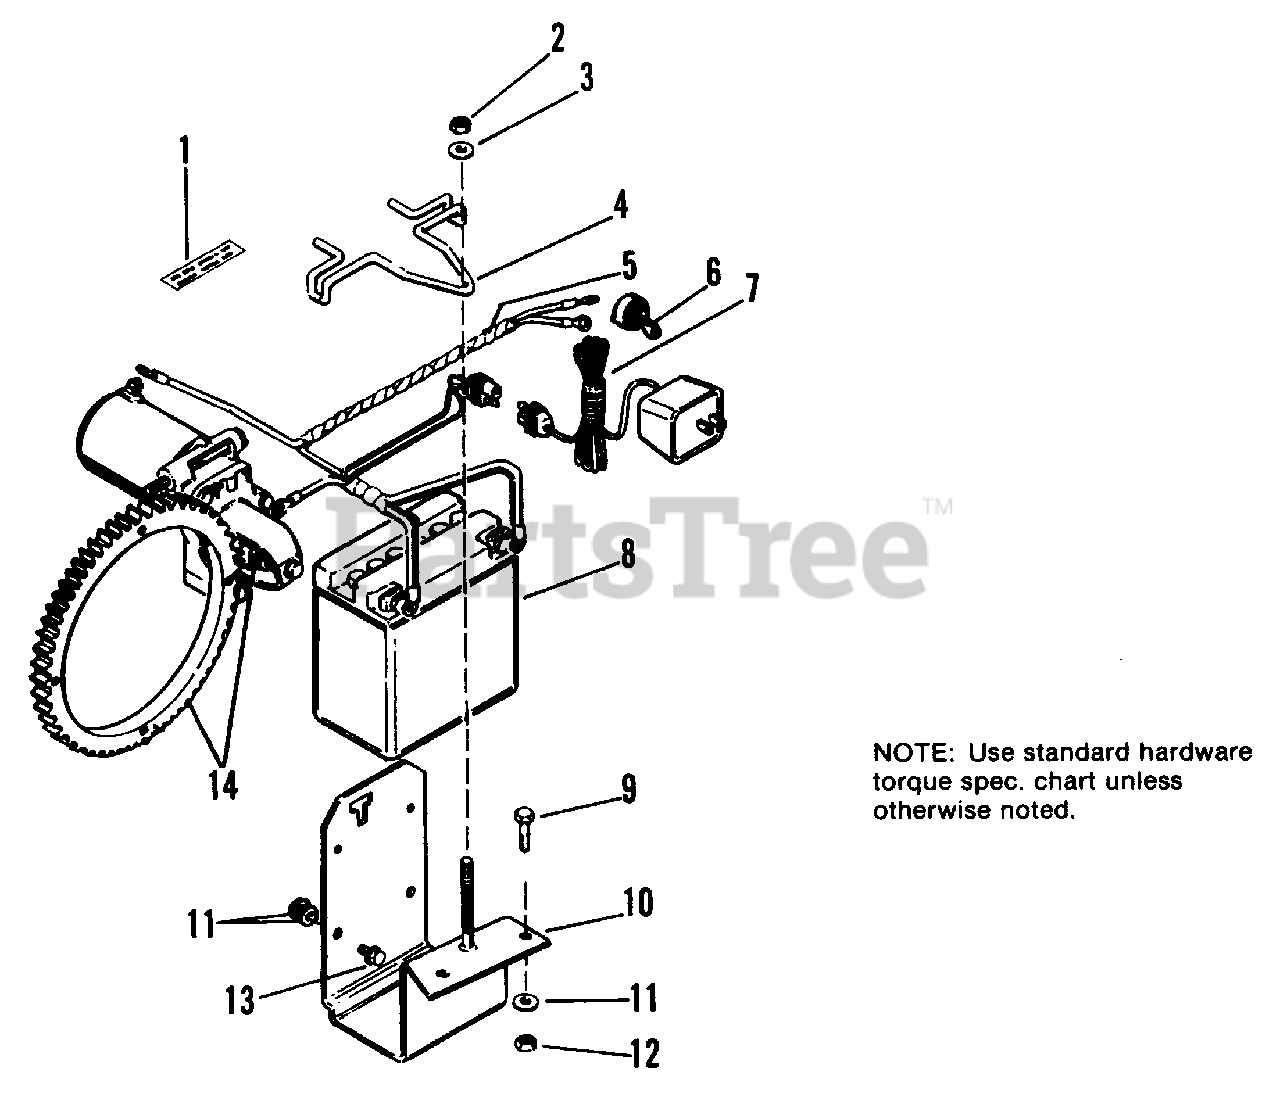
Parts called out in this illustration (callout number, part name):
1	FILM, Ignition
2	LOCKNUT, Hex, 1/4-20
3	WASHER, Plain, 1/4
4	HOLD DOWN, Battery
5	HARNESS ASSY.
6	SWITCH, Ignition Key
7	CHARGER, Battery
9	CAPSCREW, Hex Hd., 5/16-18 x 1-1/4
10	SUPPORT ASSY., Battery
11	WASHER, Plain, 5/16
12	LOCKNUT, Hex, 5/16-18
13	SCREW, Hex, Washer Hd., Taptite, 5/16-18 x 3/4
14	STARTER KIT
